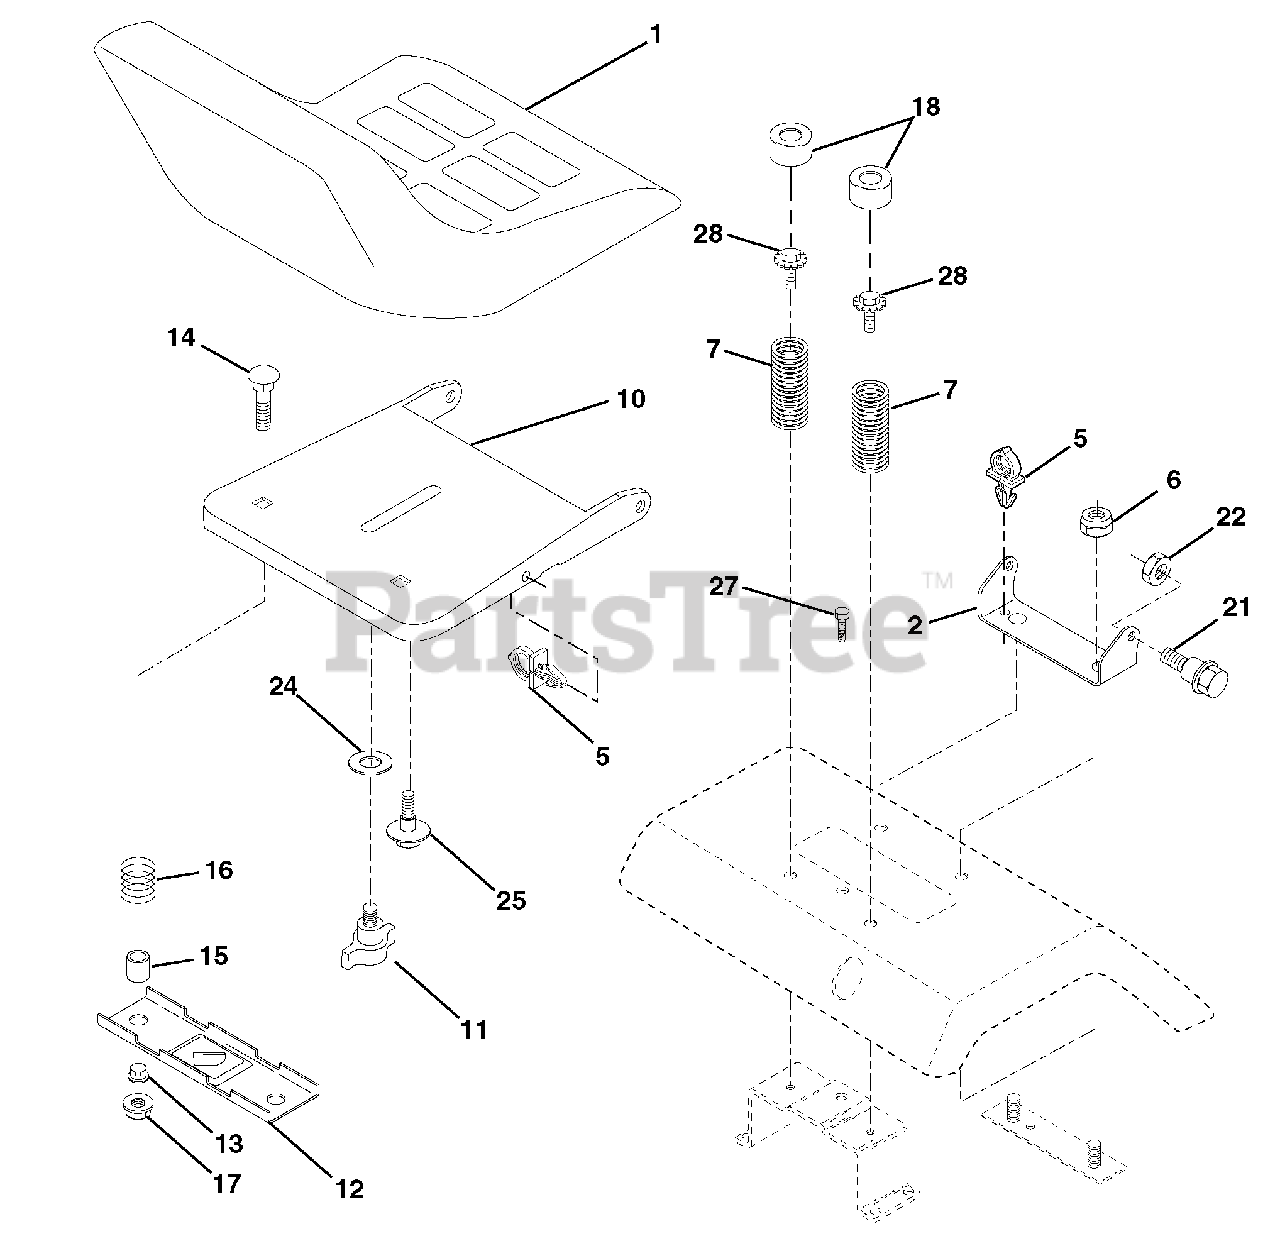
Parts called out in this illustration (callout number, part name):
2	Pivot Bracket, Seat
5	Clip, Push-in Hinged
6	Nut, Lock Hex w/Ins 3/8-16 UNC
7	Spring, Seat
10	Pan, Seat
11	Knob, Seat, Black
12	Bracket, Switch Mounting
13	Bushing, Snap, Black, Nylon
14	Bolt, Carriage 1/4-20 x 1-1/2
15	Spacer, Split
16	Spring
17	Locknut, Flange 1/4 Grade 5
18	Cap Spring Seat Blk 1.75 x 1.0
21	Bolt, Shoulder 5/16-18 Unc -2A
22	Nut Lock Hex W/Ins 5/16-18 Unc
24	Washer 17/32 x 1-3/16 x 12 Gauge
25	Bolt, Shoulder 5/16-18 x .62
27	Screw Thdrol 3/8-16 x 3/4
28	Bolt 5/16-18 UNC x 3/4 w/Sems
